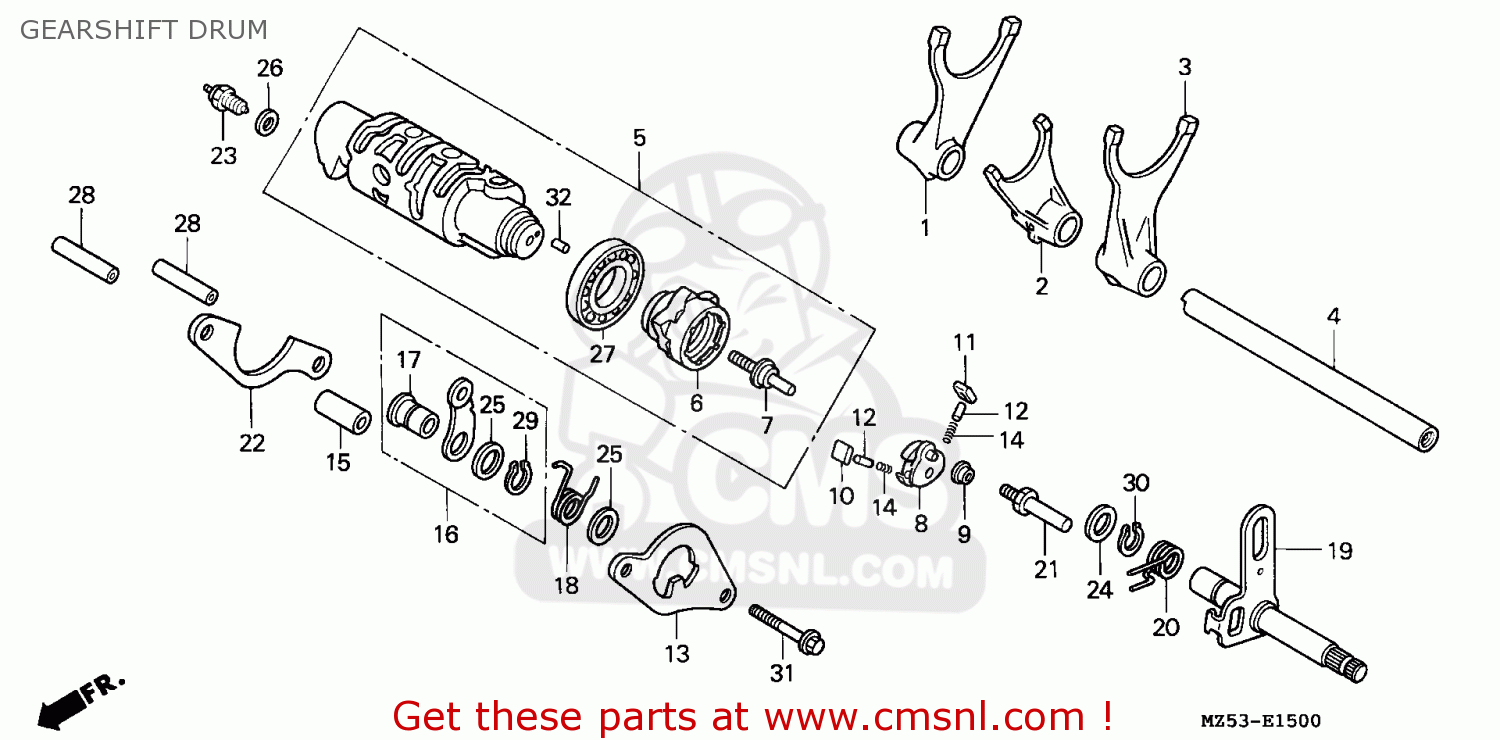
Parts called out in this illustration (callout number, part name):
1	FORK R,GEAR SHIFT
2	FORK C,GEAR SHIFT
3	FORK L,GEAR SHIFT
4	SHAFT COMP,GEAR S
5	DRUM COMP,GEAR SH
6	CENTER,GEARSHIFT
7	PIN.SHIFTER
8	SHIFTER,DRUM
9	COLLAR,DRUN SHIFT
10	PAWL A,RATCHET
11	PAWL B,RATCHET
12	PLUNGER,PAWL
13	PLATE,GUIDE
14	SPG PAWL PLUNGER
15	COLLAR,GUIDE PLAT
16	STOPPER COMP,DRUM
17	COLLAR,DRUM STOPP
18	SPG,DRUM STOPPER
19	SPINDLE COMP,SHIF
20	SPG,SHIFT RETURN
21	PIN, SHIFT RETURN
22	PLATE,SHIFT DRUM
23	SW.ASSY.,NEUTRAL
24	WASHER,THRUST 14
25	WASHER,12MM
27	B/BRG RAD N/COM
28	PIN DOWEL 8X31.5
29	CIRCLIP,EX,12
30	CIRCLIP,EX,14
31	BOLT,FLANGE,6X45
32	ROLLER,4X8
